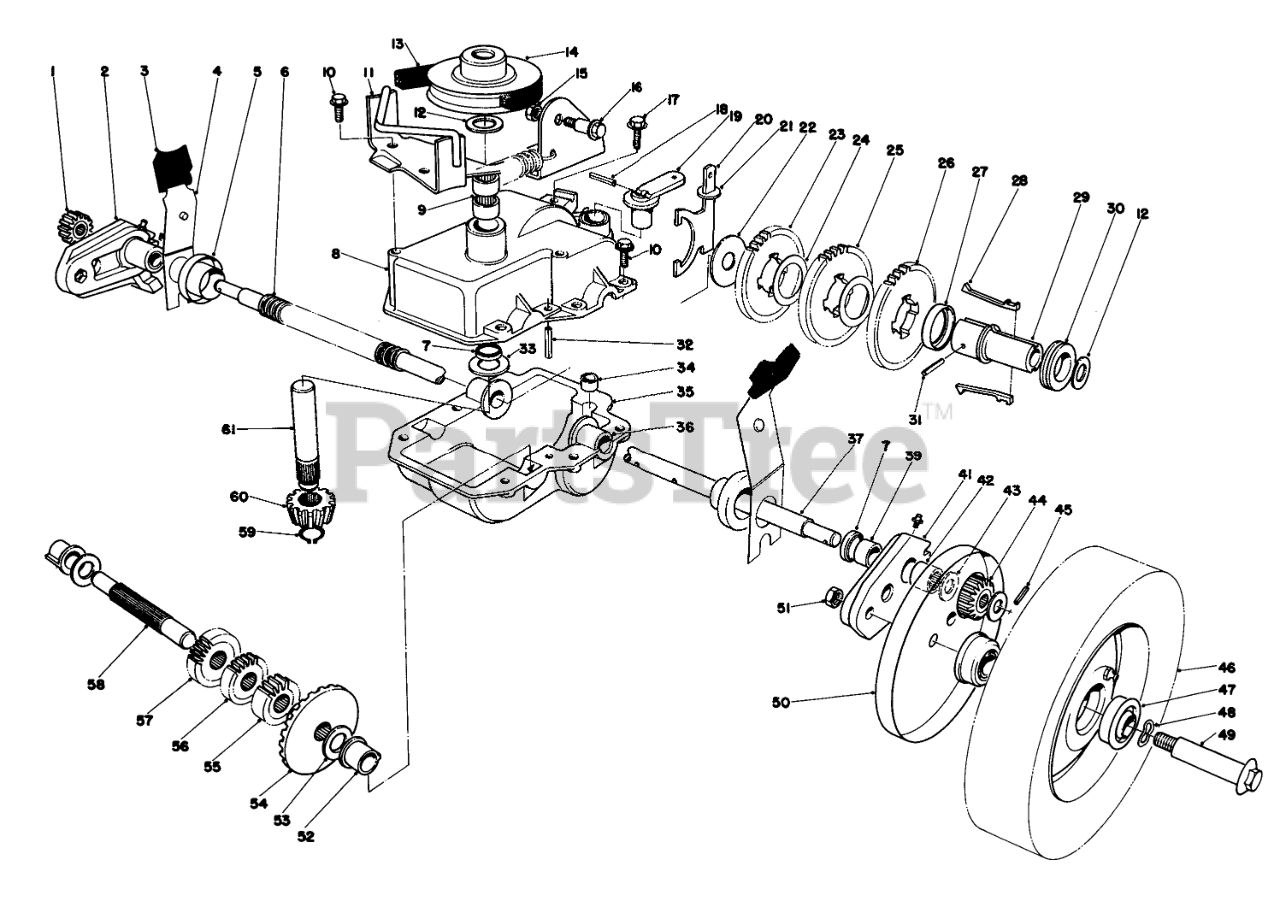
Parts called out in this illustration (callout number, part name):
1	Pinion Gear
2	Pivot Arm R.H. (Incl. Ref. #7, 39 & 42)
3	KNOB-ARM
4	Spring Arm
5	End Cap
6	Cover-Drive Shaft
7	Seal
8	Case Upper
9	Bearing
10	Screw
11	Belt Guide Bracket
12	WASHER-PLAIN
13	V-BELT
14	Pulley
15	NUT-HEX, SIDE DEFORM
16	Shoulder Bolt
17	Screw Thread Forming
18	PIN-COIL
19	LEVER-SHIFT
20	Shift Yoke
21	Yoke Washer
22	WASHER
23	Gear 38T
24	WASHER
25	Gear
26	Gear
27	Key Retainer
28	KEY-SHIFT
29	Sleeve
30	COLLAR-SHIFT
31	COIL PIN
32	ROLL PIN 3/16 X 1 IN
33	Thrust Washer
34	BUSHING-YOKE
35	LOWER GEAR CASE CAST
36	Bushing
37	OUTPUT SHAFT
39	Bushing
41	Pivot Arm L.H. (Incl. Ref. #7, 39 & 42)
42	Needle Baring
43	WASHER
44	Pinion Gear
45	Pin
46	WHEEL ASM
47	BEARING-BALL
48	SPRING WASHER
49	WHEEL BOLT
50	Cover-Wheel
51	Nut
52	Botching Shaft
53	WASHER-THRUST
54	Bevel Gear
57	Gear 18T
58	Short Shaft
59	RING-RETAINING
60	Pinion Bevel
61	Input Shaft & Pulley Assy. (Incl. Ref. #14)
